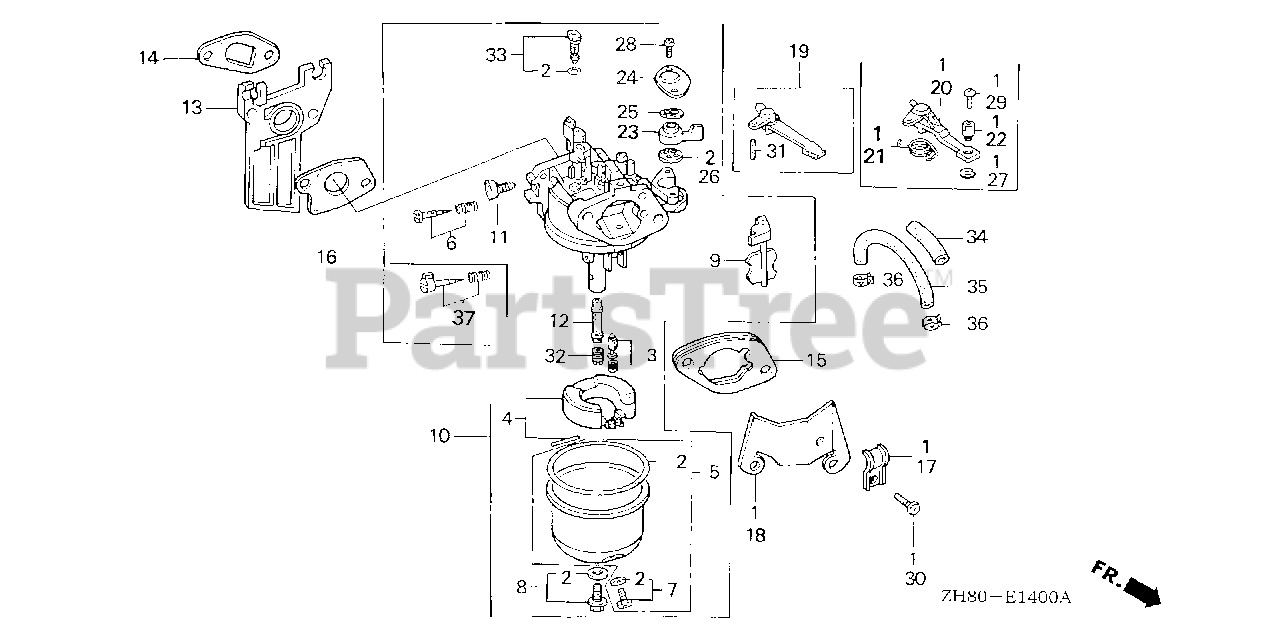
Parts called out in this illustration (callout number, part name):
2	GASKET SET
3	VALVE SET, FLOAT (SEAT NOT INCLUDED)
4	FLOAT SET
5	CHAMBER SET, FLOAT (CARBURETOR NO.)
6	SCREW SET, PILOT (CARBURETOR NO.)
7	SCREW SET, DRAIN
8	SCREW SET
9	CHOKE SET (CARBURETOR NO.)
10	CARBURETOR ASSY. (BE66E B)
10	CARBURETOR ASSY. (BE06H C)
11	SCREW, THROTTLE STOP
12	NOZZLE, MAIN (CARBURETOR NO.)
13	INSULATOR, CARBURETOR
14	GASKET, INSULATOR
15	SPACER, CARBURETOR
16	GASKET, CARBURETOR
19	LEVER, CHOKE (STD)
23	LEVER, PETCOCK
24	PLATE, LEVER SETTING
25	SPRING, PETCOCK LEVER
26	GASKET, PETCOCK
28	SCREW, PAN (3X6)
28	SCREW, PAN (3X8) (CARBURETOR NO.)
31	PIN, SPRING (2X12)
32	JET, MAIN (#72) (CARBURETOR NO.)
32	JET, MAIN (#65) (CARBURETOR NO.)
32	JET, MAIN (#68) (CARBURETOR NO.)
32	JET, MAIN (#70) (CARBURETOR NO.)
32	JET, MAIN (#65)
32	JET, MAIN (#70)
33	JET SET, PILOT (#35) (CARBURETOR NO.)
33	JET SET, PILOT (#38) (CARBURETOR NO.)
37	SCREW SET, PILOT (CARBURETOR NO.)
